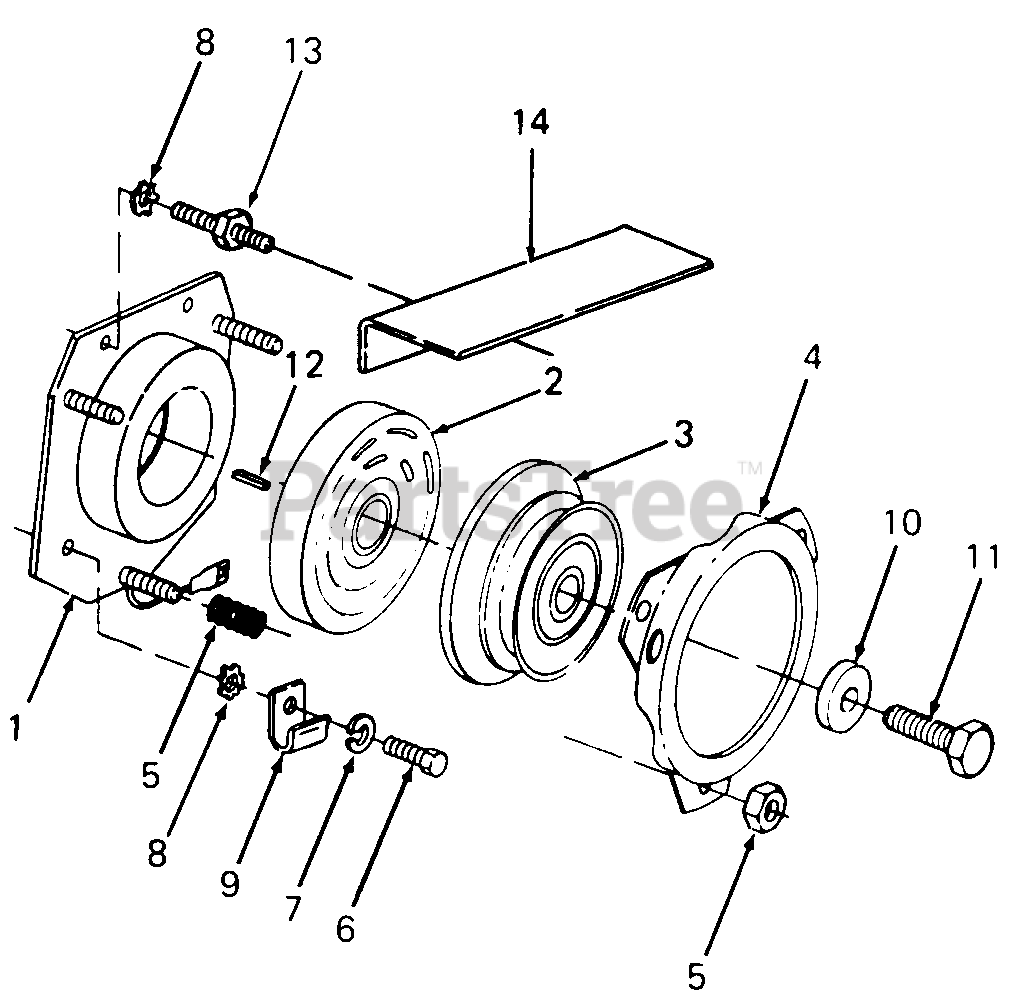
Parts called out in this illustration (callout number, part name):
4	Drum, Brake
5	Spring & Nut Kit
6	Screw, Hex Cap, 7/16-14 X .75 Lg GR5
7	Washer, Lock, 7/16
8	Washer, Ext. Lock, .45 X .75 X .035 Thk
9	Clamp, Cable
10	Washer, Flat, .47 X 1.5 X .225 Thk
11	Screw, Hex Cap, 7/16-20 X 1.25 Lg GR5
12	Key, Square, 1/4 X .75 Lg
13	Stud, 7/16-14 Trd
14	Baffle, PTO
